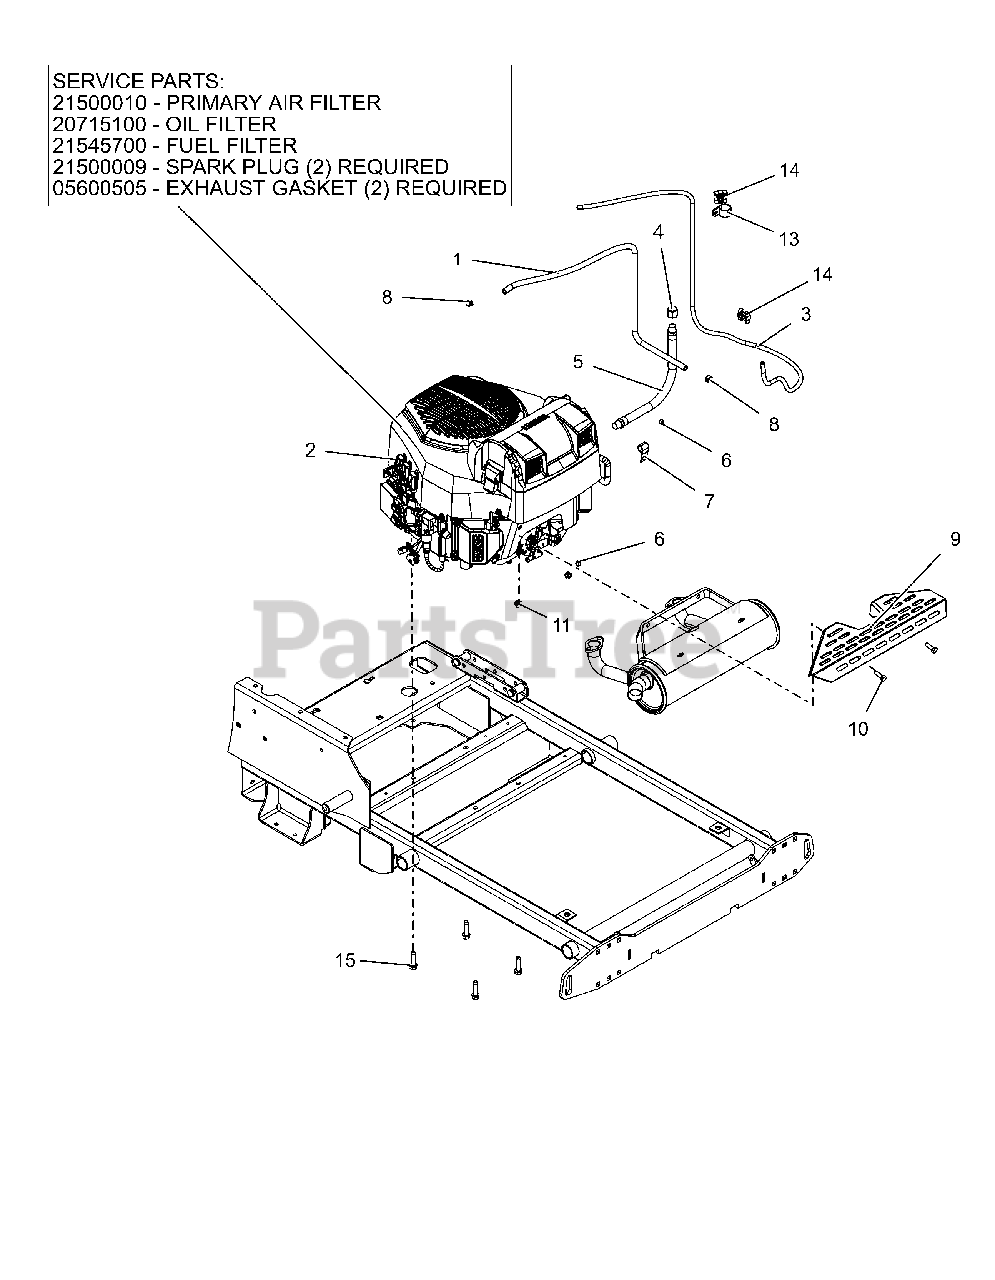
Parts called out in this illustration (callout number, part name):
1	HOSE, .25 LOW-PERM BULK GAS
2	ENGINE, KOHLER EZT725
2	AIR CLEANER, KOHLER CONFIDANT
2	OIL FILTER KOHLER
2	FILTER-FUEL KOHLER COURAGE PRO
2	PLUG, SPARK KOHLER
2	GASKET, MUFFLER KOHLER TWIN
3	HOSE, .188 LOW-PERM BULK GAS
4	PIPE CAP 3/8 NPT FEMALE
5	HOSE,HYD .38-14-0K M6N0-M6N0
6	CLAMP-HOSE, SPRING .188
8	CLAMP, FUEL LINE
9	GUARD, MUFFLER
10	@BLT-HEX .31-18X1.00 GR5 YWZC
11	@NUT-LK-NYL-FLG .31-18 YWZC
13	CLAMP, COUSHIONED STEEL REV
14	CLIP, T, .38-.50
15	@SCR-TAP .38-16X1.50 HWH TR YZ
